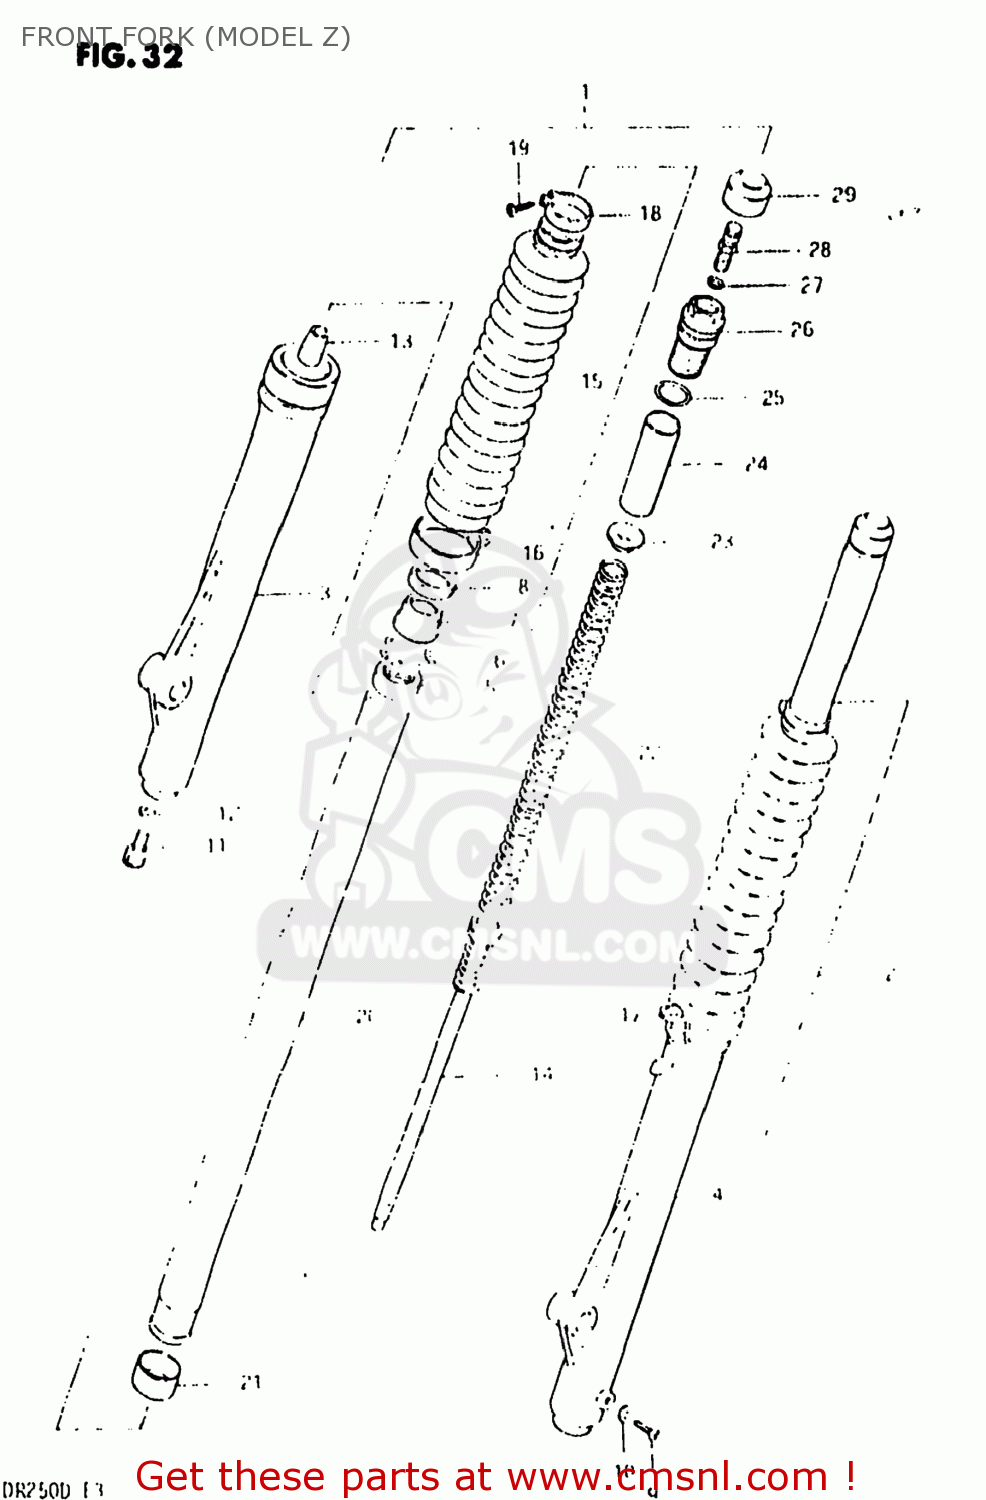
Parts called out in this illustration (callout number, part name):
1	DAMPER ASSEMBLY,RIGHT
2	DAMPER ASSEMBLY,LEFT
3	TUBE,OUTER,RIGHT
4	TUBE,OUTER,LEFT
5	OIL SEAL,FRONT FORK
6	7
7	SEAL,DUST
8	CASE,DUST SEAL
9	SCREW
10	GASKET,DRAIN,PLUG (NAS)
11	BOLT,FORK CYLINDER(10X25)
12	GASKET (NAS)
13	PIECE,OIL LOCK
14	CYLINDER,FRONT FORK
15	BOOT
16	BAND,FRONT FORK COVER
17	BAND,FRONT FORK COVER
18	BAND,BOOT
19	SCREW
20	TUBE,FORK,INNER
21	PISTON
22	SPRING,FRONT FORK
23	GUIDE,FRONT FORK SPRING C
24	COLLAR,SPRING
25	O RING
26	CAP,FORK INNER TUBE
27	O-RING
28	VALVE,FRONT FORK AIR
29	CAP
